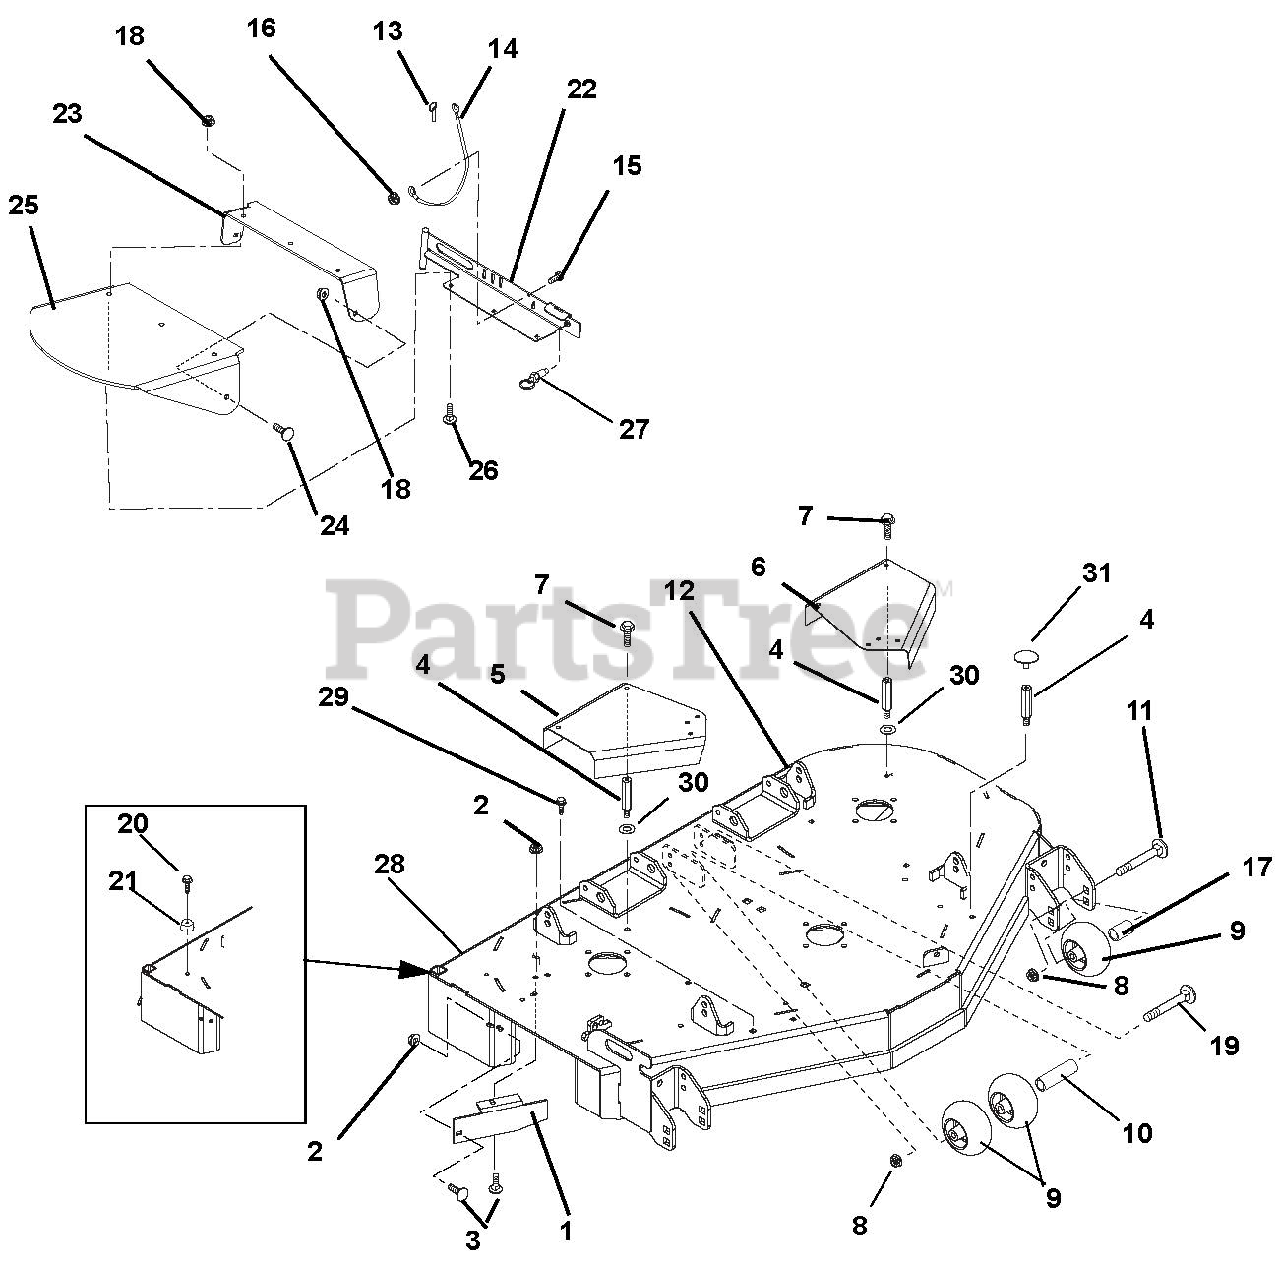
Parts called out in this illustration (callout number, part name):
1	44 in. & 48 in. Rear Discharge Baffle
2	Nut, .31-18 Nyloc Flange
3	Bolt, Round Head Square Neck .31-18 x 1.00 Grade 5
4	Standoff, .38-16 x .50 Self Tapping
5	Right Hand Spindle Guard
6	44 in., 48 in., & 52 in. Left Hand Spindle Guard
7	Bolt, SEMS .31-18 x .62
8	Nut .50-13 Nyloc Flange
9	Anti-Scalp Wheel
11	Bolt-Round Head Square Neck .50-13X5.00
12	44 in. Side Discharge Mower Deck
13	Pin, Spring Ball .375 OD x 1.50
14	Cable, 5-in.
15	Bolt, Hex .25-20 x .75 Grade 5
16	Nut, Locking Top Flange .25-20
17	Spacer, .510 x .625 x 3.35
18	Nut, .38-16 Nyloc Flange
19	Bolt, Round Head Square Neck .50-13 x 8.50
20	Screw, Tapping .31-18 x .75 Hex Washer Head Thread
21	Bumper, Recessed 1.50 x .63 , .31 Thru Hole
22	44 in. & 48 in. Discharge Chute Mounting Weldment
23	Rubber Discharge Chute Support
24	Bolt, Round Head Square Neck .38-16 x 1.00 Grade 5
25	Chute, Rubber Discharge
26	Bolt, Round Head Square Neck .38-16 x 1.25 Grade 5
27	Pin, Pull
28	Deck, 44" Side Discharge
29	Screw, Tapping .38-16 x .50
30	Washer, Internal Lock .375
31	Bumper, Rubber
